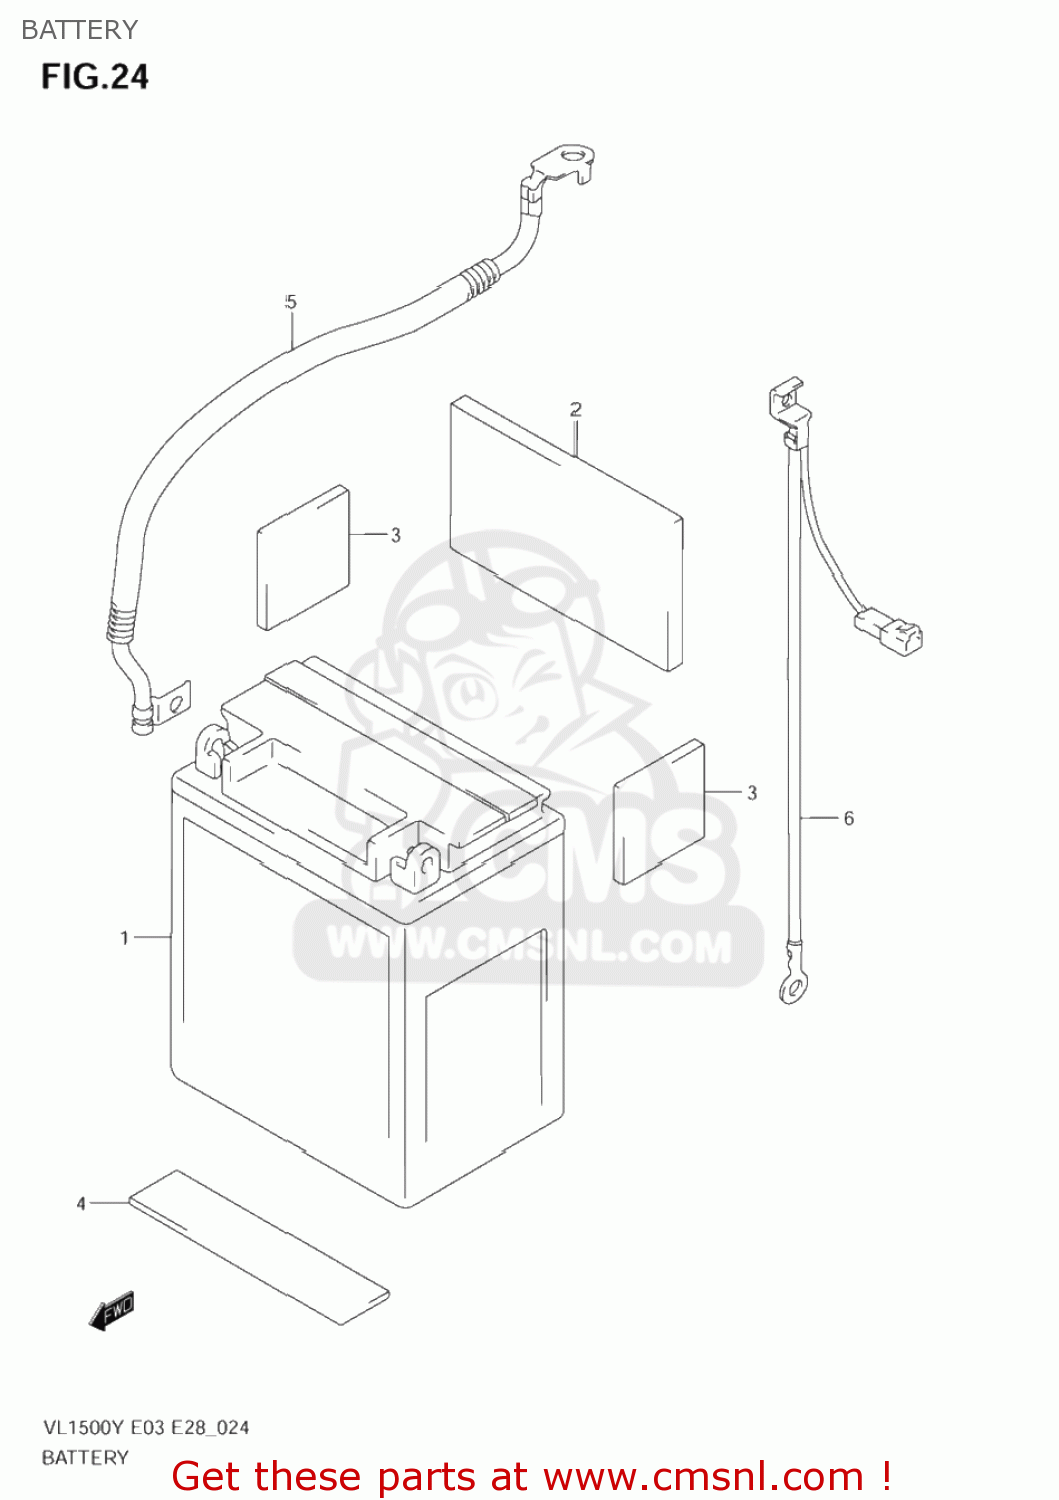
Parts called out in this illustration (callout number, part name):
1	BATTERY ASSEMBLY 12V14AH,F
2	PROTECTOR(50X50X5)
3	PROTECTOR(170X95X3.0)
4	PROTECTOR,BATTE
5	WIRE,BATTERY PLUS LEAD
6	WIRE,BATTERY MINUS LEAD
